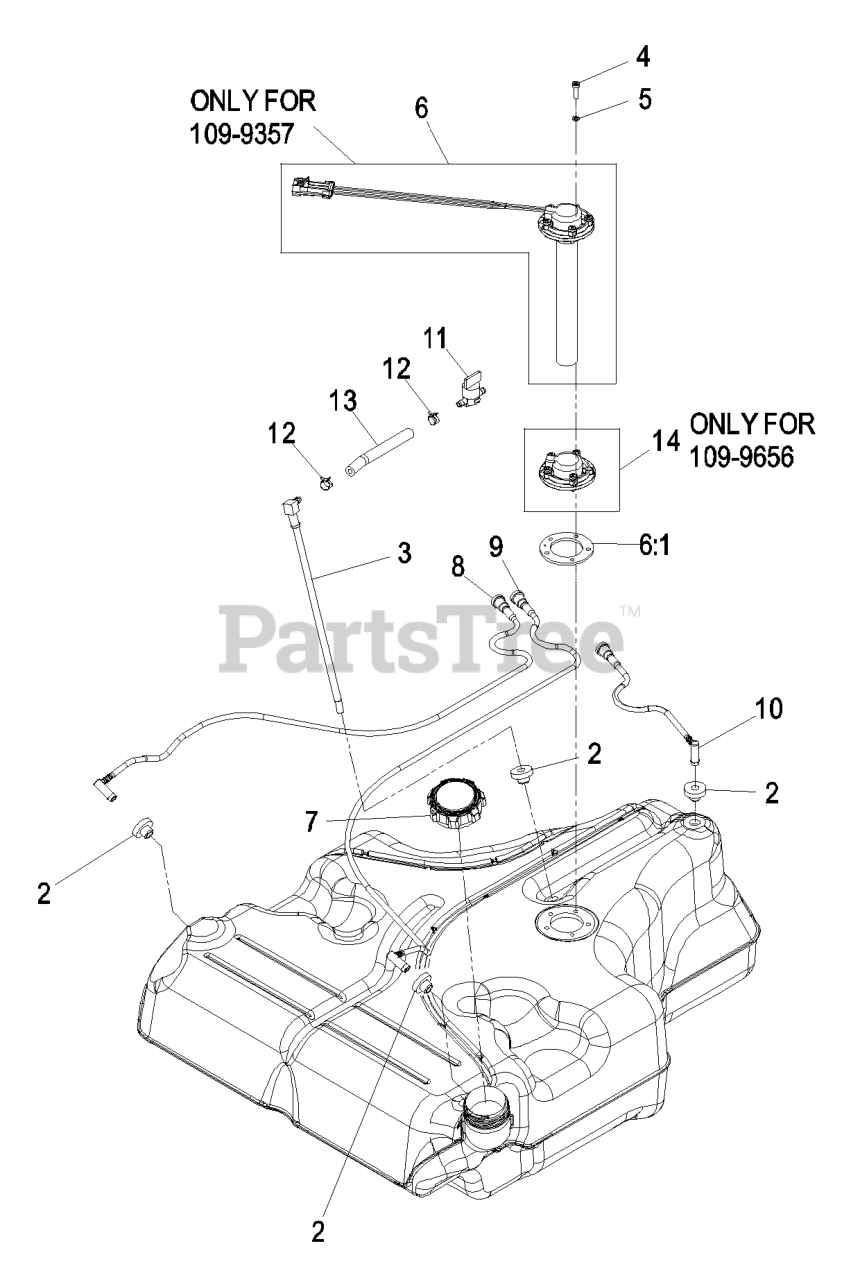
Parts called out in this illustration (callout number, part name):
2	BUSHING
4	SCREW-PAN
5	WASHER-LOCK
6:1	GASKET-SENDER, FUEL
11	VALVE-FUEL
12	CLAMP-HOSE
13	HOSE-FUEL
14	Cover, Plastic Fuel Tank
